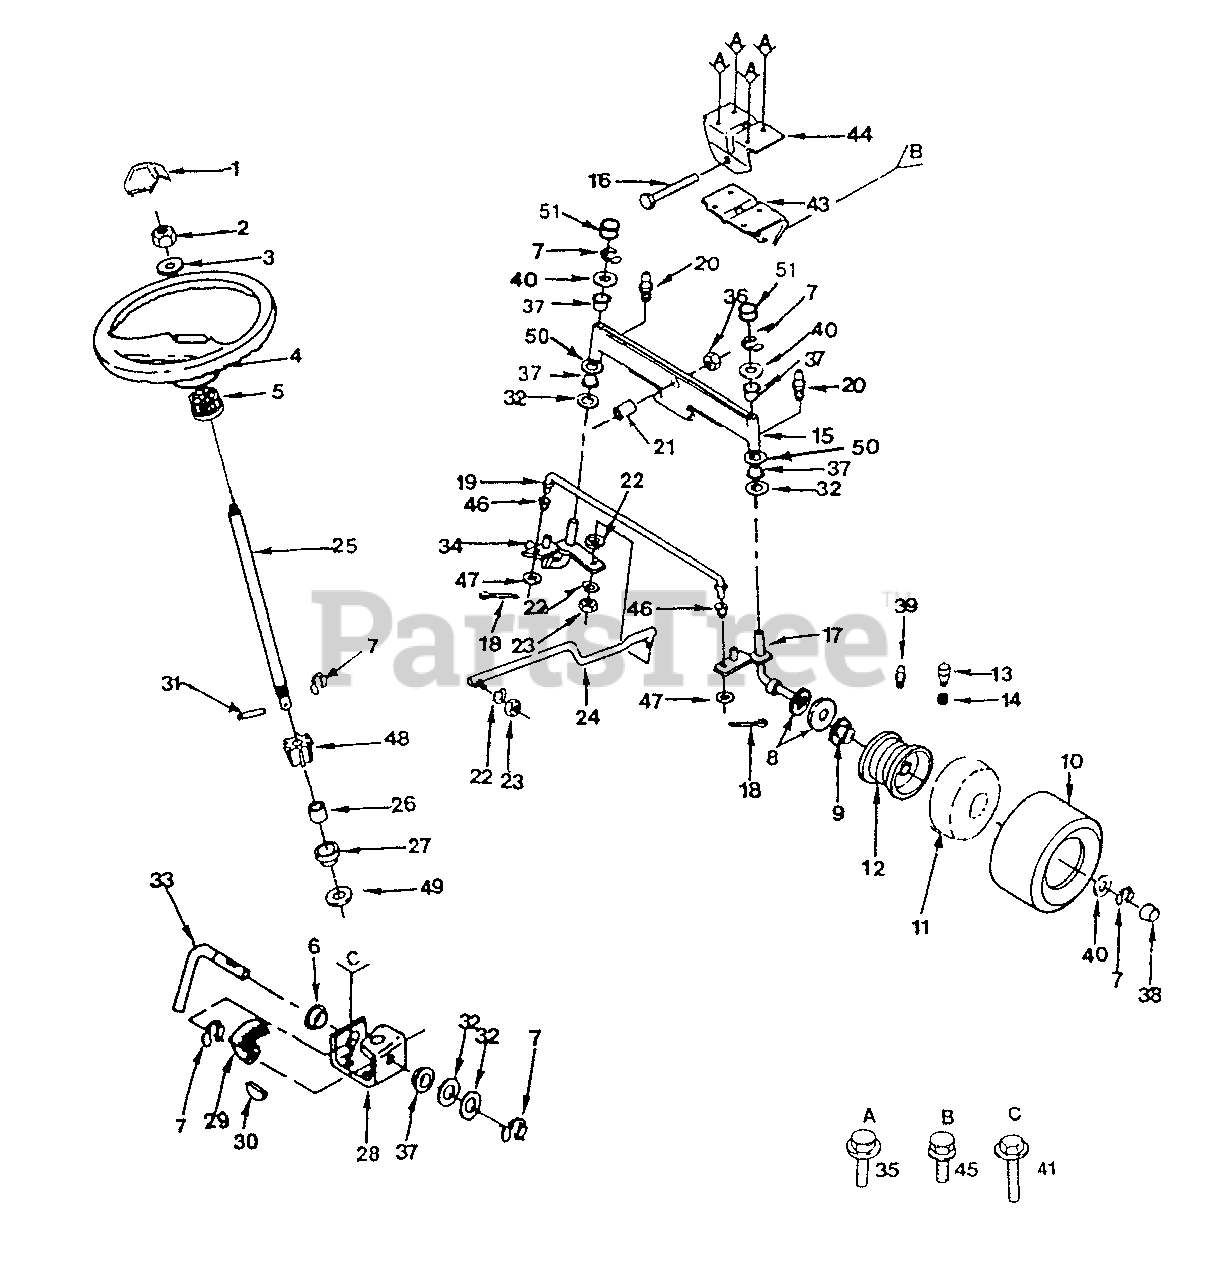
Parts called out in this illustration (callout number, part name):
1	Insert, Steering Wheel
2	Nut, Hex Jam Toplock 1/2 - 20
3	Washer 17/32 x 2 - 1/4 x .160
4	Steering Wheel
5	Adapter, Steering Wheel
6	Nyliner, Snap-in
8	Washer 25/32 x 1 - 1/4 x 16 Ga.
9	Bearings, Wheel, Front
10	Tire, 15 x 6.00 - 6 (Tubeless)
11	Tube, Tire (not furnished with Tractor)
12	Rim Assembly - 6" Front
13	Stem, Valve
14	Cap, Valve
15	Axle Assembly, Front
16	Bolt, Hex 5/8-11 x3-3/4
17	Spindle Assembly, R.H.
18	Pin, Cotter 1 /8 x 3/4
19	Tie Rod
20	Fitting, Grease
21	Spacer Bearing, Front Axle
22	Lockwasher 3/8
23	Nut, Hex 3/8 - 24
25	Shaft, Steering
27	Bushing, Steering Rod
28	Bracket Assembly, Steering
29	Gear, Sector
30	Woodruff Key 3/16 x 3/4
31	Drive Pin 3/16 x 1
32	Bearing Thrust
33	Rod, Steering
34	Spindle Assembly, L.H.
35	Screw, Hex Washer Hd. Thread Forming Type TT 3/8 -16 x 3/4
36	Nut, Flange 5/8 - 11
39	Grease Fitting
40	Washer 25/32 x 1 - 5/8 x 16 Ga.
41	Screw, Hex Washer Thrdl 3/8 - 16 x 3/4
43	Support, Saddle, Front
44	Support, Saddle, Rear
45	Screw, Hex Washer Thd. Rolling 5/16-18x1/2
46	Bushing
47	Washer 13/32 x 7/8 x 16 Ga.
48	Gear, Pinion
49	Washer, Hardened
50	Washer 27/32 x 1 - 1/4 x 16 Ga.
51	Spindle Cap
